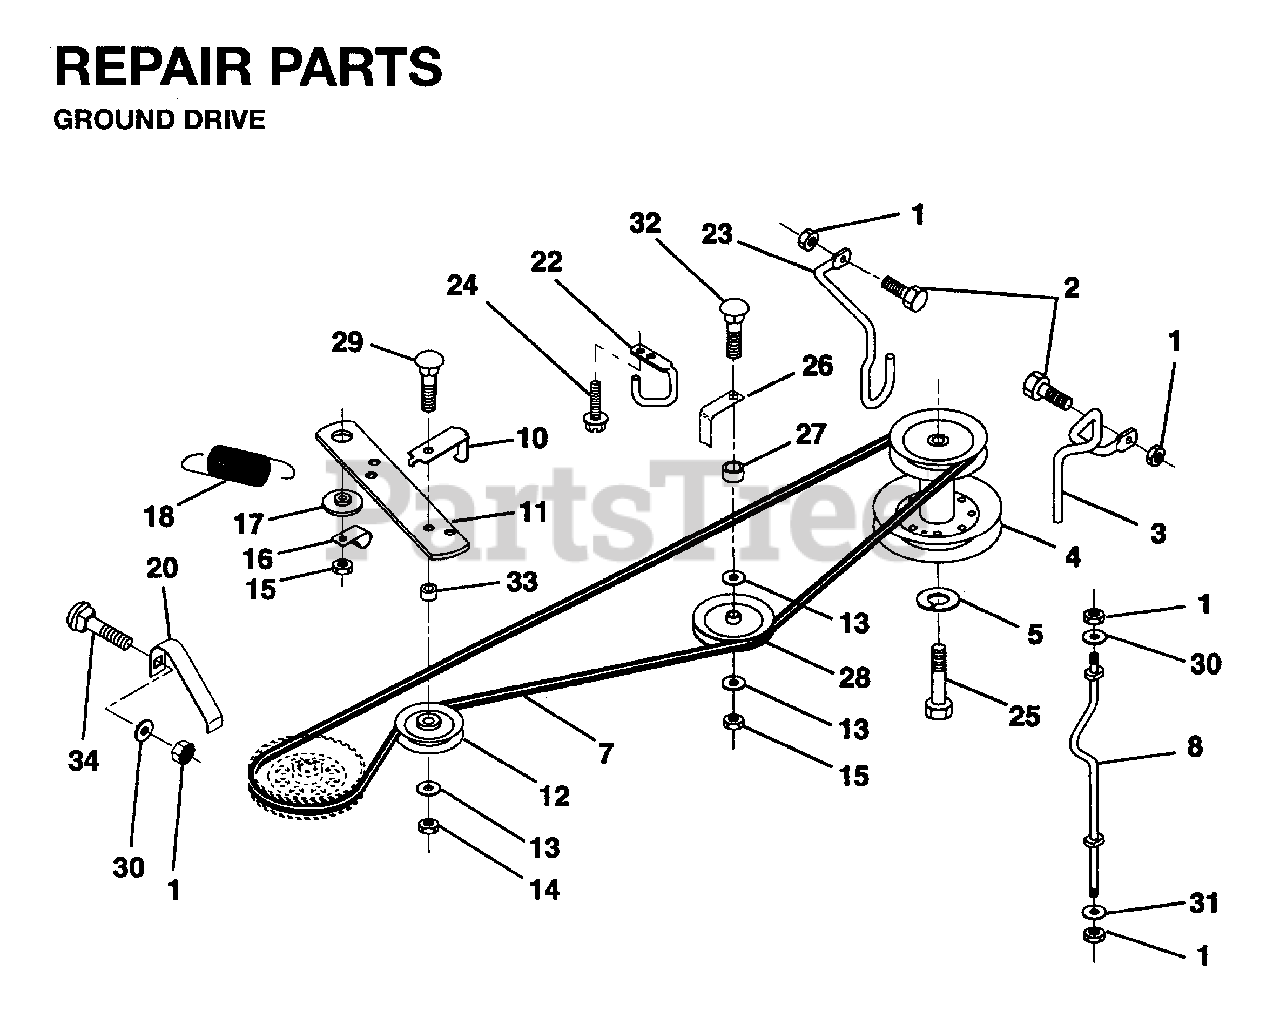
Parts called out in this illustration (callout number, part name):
1	NUT.71038.31-18.HEX.NYLOCK
2	BOLT
4	ENGINE PULLEY
5	LOCKWASHER
7	V-BELT 77.75
10	KEEPER, BELT
11	ARM/GROUND DRIVE CLUTCH
12	PULLEY.IDLER.FLAT
13	WASHER
14	LOCKNUT
15	LOCKNUT
16	CLIP,INSULATOR
17	SPACER RETAINER
18	SPRING.EXTENSION
20	KEEPER, BELT
22	KEEPER,FRA DR BEL
23	KEEPER-MOWER DRIVE LH
24	BOLT
26	KEEPER, BELT
28	PULLEY.IDLER.V.
30	WASHER - 15X7.3X1.6
31	WASHER - 15X7.3X1.6
32	BOLT
33	SPACER NLA
34	BOLT
